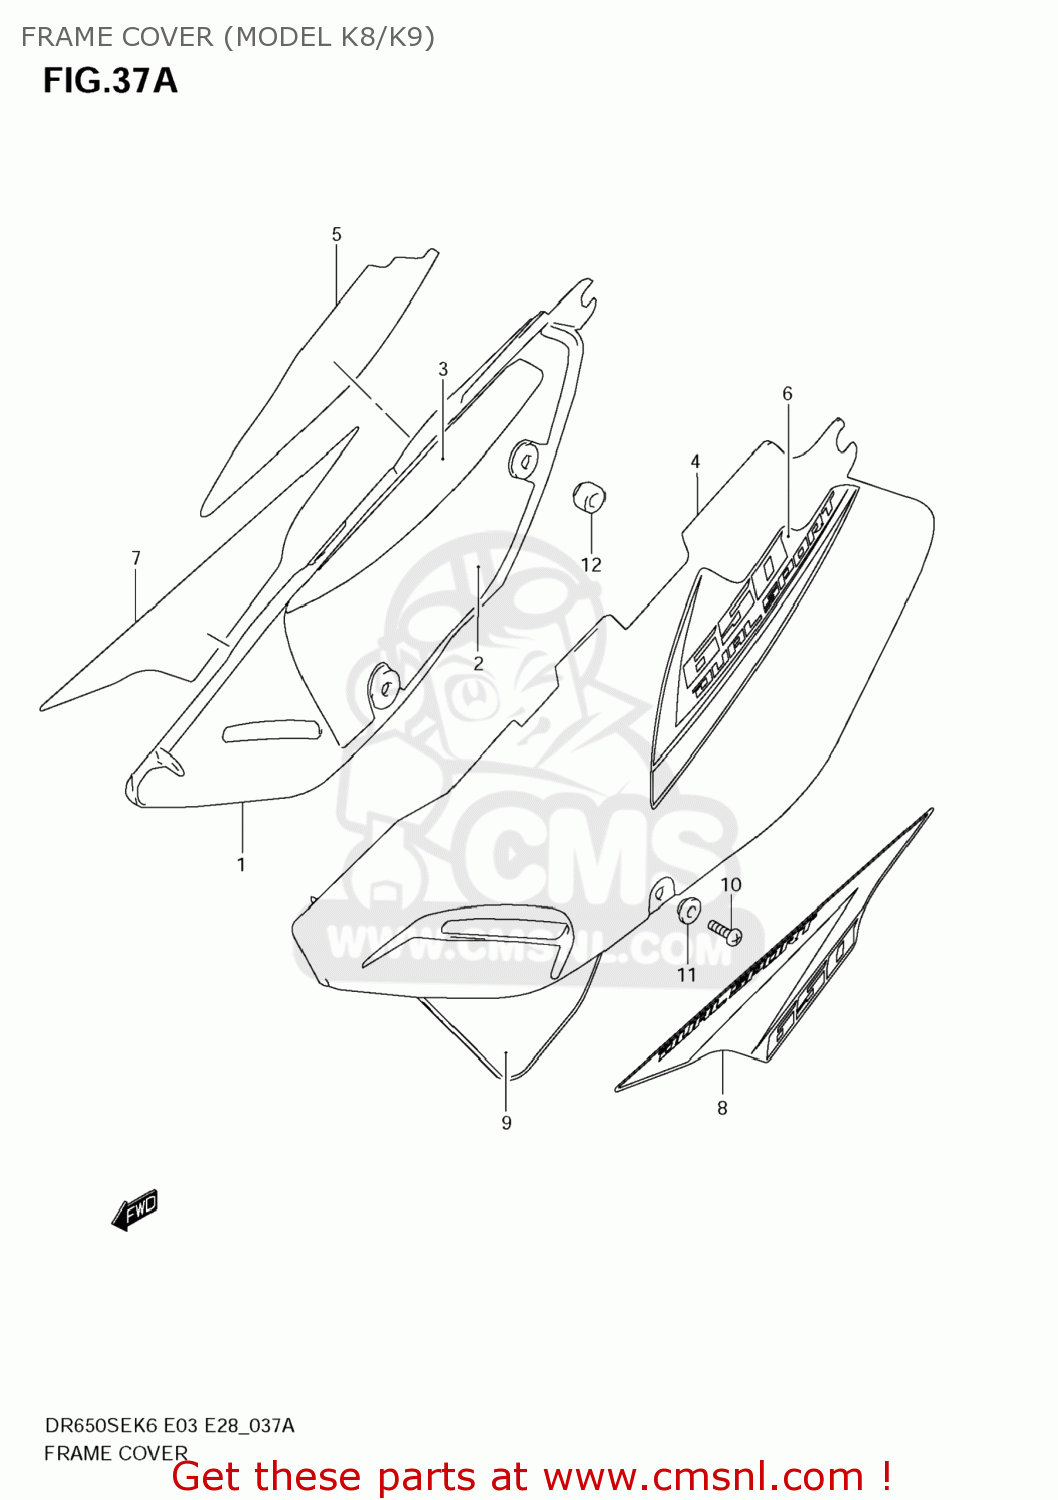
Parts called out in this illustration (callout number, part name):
1	COVER,FRAME,R(WHITE)
2	SHIELD,FRAME COVER,R NO.1
3	SHIELD,FRAME COVER,R NO.2
4	COVER,FRAME,L(WHITE)
5	TAPE,FRAME COVER,R
6	TAPE,FRAME COVER,L
7	TAPE,FRAME COVER,R
8	TAPE,FRAME COVER,L
9	TAPE,LWR
10	SCREW
11	WASHER
12	CUSHION
